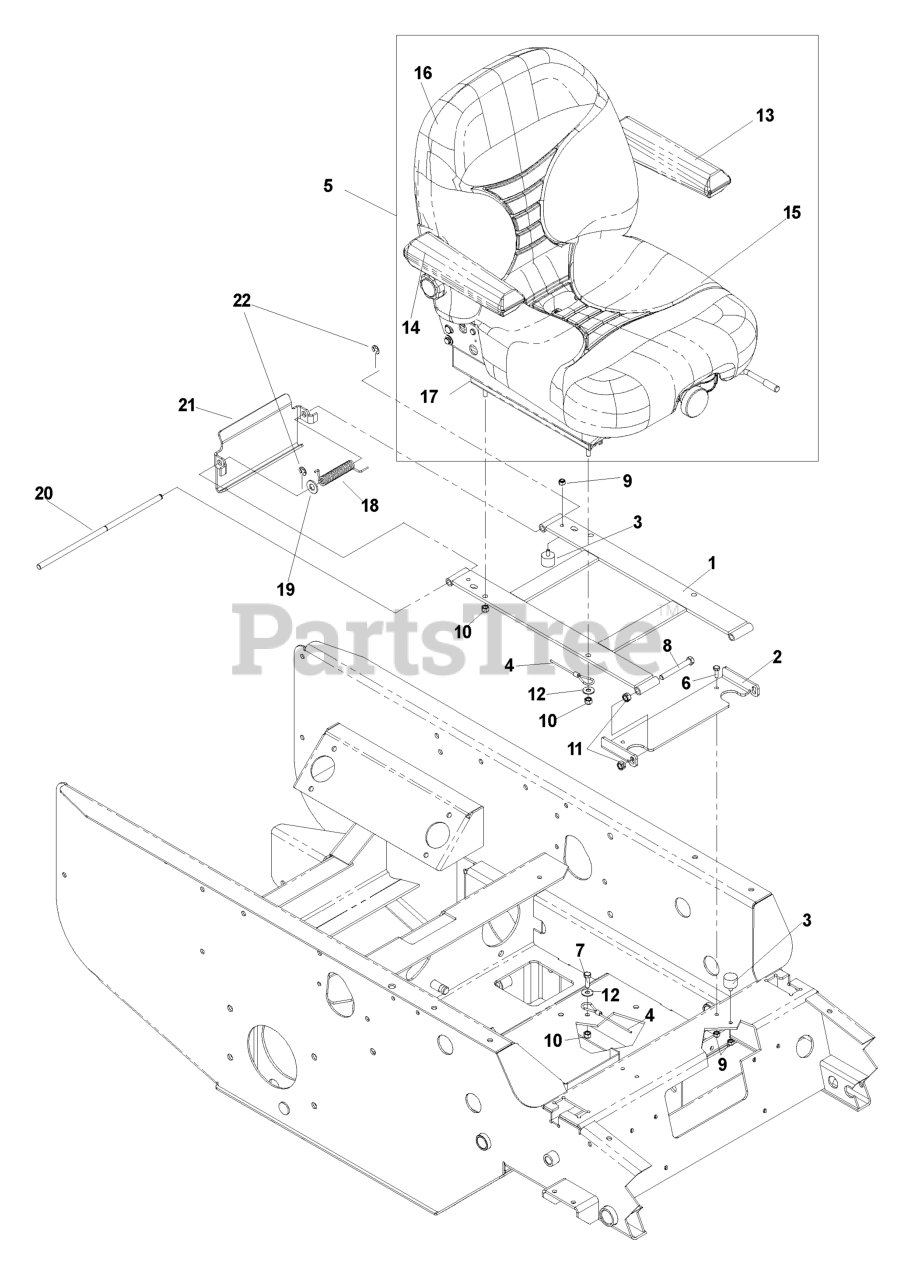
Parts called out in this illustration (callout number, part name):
1	SEAT MOUNT WLDMT
2	SEAT BKT. W/PAINT
3	STUD/PLATE MOUNT
4	SEAT LANYARD
5	Seat suspension
6	HCS 1/4C X 3/4 HCS
7	HCS 5/16C X 1
8	HCS 3/8C X 3
9	NUT 1/4-20 HEX FLG LK ZD
10	NUT 5/16 NYLOC
11	NUT 3/8C CENTERBLOCK
12	WASHER 5/16 FLAT
13	ARMREST KIT, LH
14	ARMREST KIT, RH
15	SEAT CUSHION KIT
16	BACK CUSHION KIT
17	SLIDE KIT, SEAT ADJ
18	TORSION SPRING (SEAT)
19	WASHER 3/8 SAE FLAT
22	E RING 3/8"
